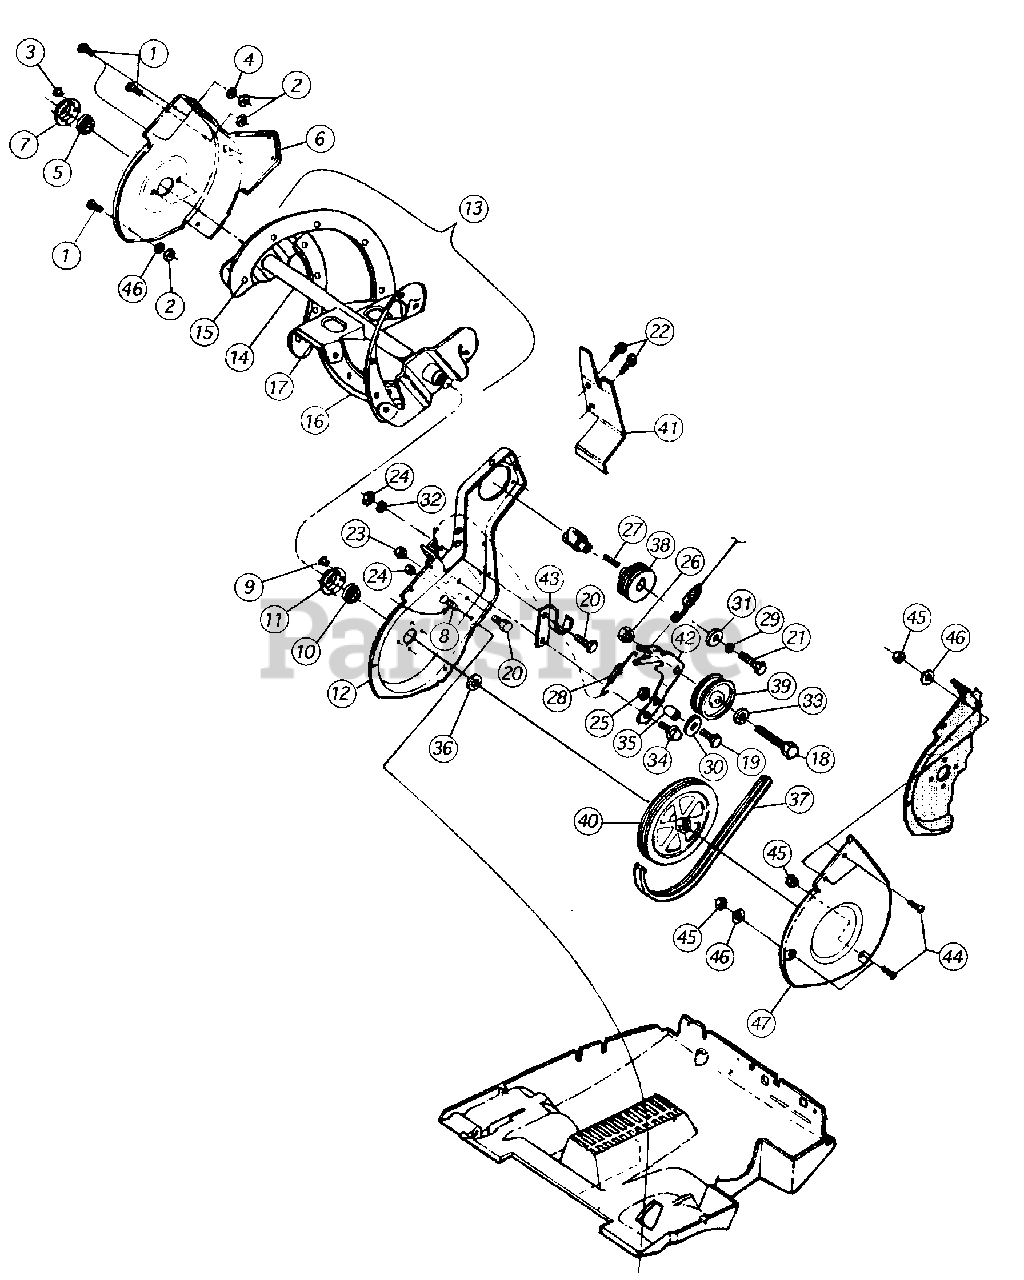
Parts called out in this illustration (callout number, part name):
1	Screw, Truss Machine #10-24 x .5
2	Nut, Hex Sems, #10-24
3	Rivet, .252 x .31
4	Washer, Flat, .203 x .41 x .04
5	Ball Bearing, Auger Axle
8	Screw, Hex Cap, 1/4-20 x .625
9	Rivet, .252 x .31
10	Ball Bearing, Auger Axle
11	Retainer, Bearing
14	Auger Assembly, Welded
15	Rivet, Truss
16	Auger Blade, Rubber
17	Auger Paddle, Rubber
18	Screw, Hex Cap 3/8-16 x 1.5 GR5
19	Screw, Hex Cap 1/4-20 x 1.0 GR5
20	Screw, Hex Cap 1/4-20 x .75 GR5
21	Screw, Hex Cap, 5/16-18 x .86
22	Screw, Hex Wash Hd 10-24 x .5
23	Nut, Hex Sems, 5/16-18
24	Nut, Hex Sems, 1/4-20
25	Nut, Hex Center Lock, 1/4-20
26	Nut, Hex Flange Lock, 3/8-16
27	Key, Square, 3/16 x 1.0
28	Spring, Extension
29	Washer, Lock, 5/16
30	Washer, Flat, .344 x 1.12
31	Washer, Flat, .385 x .87 x .092
32	Washer, Flat, .25 x .62
33	Washer, Flat, .406 x .81 x .051
34	Shoulder Screw .498 x .15: 5/16-18
35	Spacer, Belt Brake
36	Spacer, Auger PUlley
37	Belt, Auger Drive
38	Pulley, Engine
39	Pulley, Flat Idler w/ Flanges
40	Pulley, Auger
41	Shield, Belt
42	Idler Arm
43	Bracket, Belt
44	Screw, Truss Machine #10-24 x .62
45	Nut, Hex Sems #10-24
46	Washer, Flat, .218 x .62 x .063
